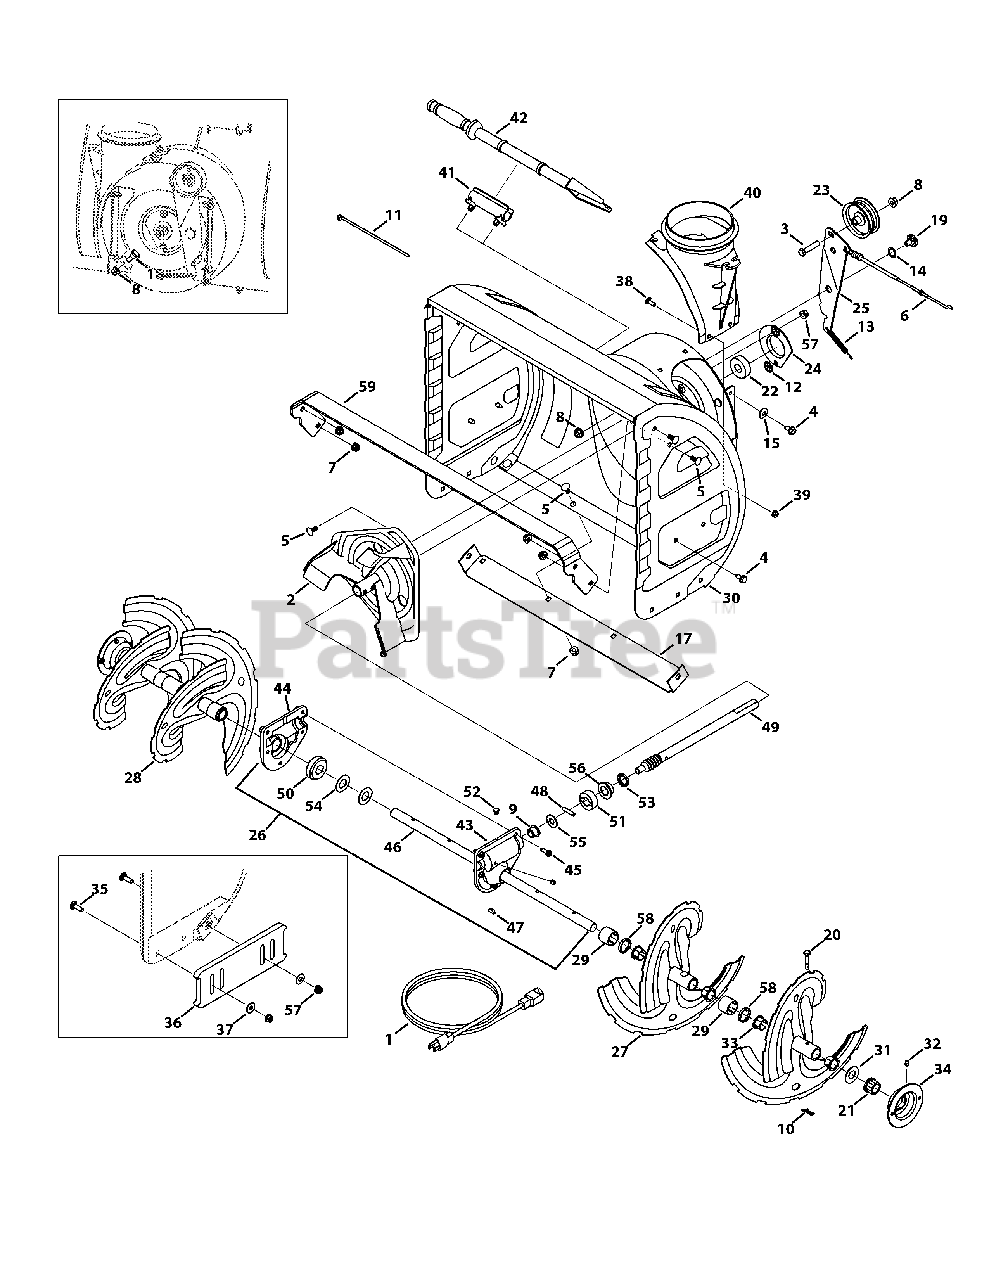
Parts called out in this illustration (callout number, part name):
1	Extension Cord
2	Impeller Assembly
3	Hex Bolt, 3/8-16 x 1.75
4	Screw, 5/16-18 x .750
5	Carriage Bolt, 5/16-18 x .750 (24", 26")
5	Crg. Bolt, 5/16-18 x .750 (28", 30")
6	Auger Clutch Cable
7	Flange Lock Nut, 5/16-18 (24", 26")
7	Hex Nut, 5/16-18 (28", 30")
8	Flange Lock Nut, 3/8-16
9	Flange Bearing, .50 x .75 x .59
10	Bow Tie Cotter Pin
11	Cable Tie
12	Push-On Nut, .25 Dia.
13	Extension Spring, .38 OD x 4.59
14	Wave Washer, .625 x .885 x .0175
15	Bell Washer, .337 X.867 X .057
15	Bell Washer, .340 x .872 x .060
17	Shave Plate, 30"
17	Stainless Steel, Shave Plate, 30"
17	Shave Plate, 28"
17	Stainless Steel, Shave Plate, 28"
17	Shave Plate, 26"
17	Stainless Steel, Shave Plate, 26"
17	Shave Plate, 24"
18	Shoulder Screw, 3/8-16 x .496 x .336
19	Shoulder Screw, 3/8-16 x .625 x .17
21	Hex Flange Bearing
22	Flange Ball Bearing, .75 x 1.85
23	Flat Idler Pulley
24	Bearing Housing
25	Auger Idler Bracket
26	Gearbox Assembly, Auger, 30"
26	Gearbox Assembly, Auger, 28"
26	Gearbox Assembly, Auger, 26"
26	Gearbox Assembly, Auger, 24"
27	Spiral Assembly - LH
28	Spiral Assembly - RH
29	Spacer, 1.25 x .75 x 1.00
30	Auger Housing, 30"
30	Auger Housing, 28"
30	Auger Housing, 26"
30	Auger Housing, 24"
31	Flat Washer, .76 x 1.49 x .06
32	Drive Lube Fitting
33	Flange Bushing, .800 x .910
34	Bearing Housing
35	Spacer, Carriage, 5/16-18 x 1.00
36	Deluxe Slide Shoe
37	Washer, Flat, .349 x .879 x .063
38	Carriage Screw, 1/4-20 x 0.75
39	Flange Lock Nut, 1/4-20
40	Chute Adapter
41	Clean-out Tool Mtg. Bracket
42	Clean-Out Tool
43	Housing Assembly - RH
44	Housing Assembly - LH
45	Screw, 1/4-20 x 0.75
46	Axle, Auger, 30"
46	Axle, Auger, 28"
46	Axle, Auger, 26"
46	Axle, Auger, 24"
47	Hi-Pro Key
48	Dowel Pin, .25OD x 1.25
49	Worm Shaft
50	Worm Gear, 20T, 28", 30"
50	Worm Gear, 20T, 24", 26"
51	Thrust Collar
52	Plug, 1/4 x .437
53	Oil Seal, .75 x 1.131 x .188
54	Flat Washer, .76 x 1.5
55	Flat Washer, .51 x 1.12 x .06
56	Flange Bearing, .75 x 1.00 x .59
57	Flange Lock Nut
58	Spacer, 1.25 OD x .75 ID x 3/16 Lg
59	Housing Support Bracket, 30"
